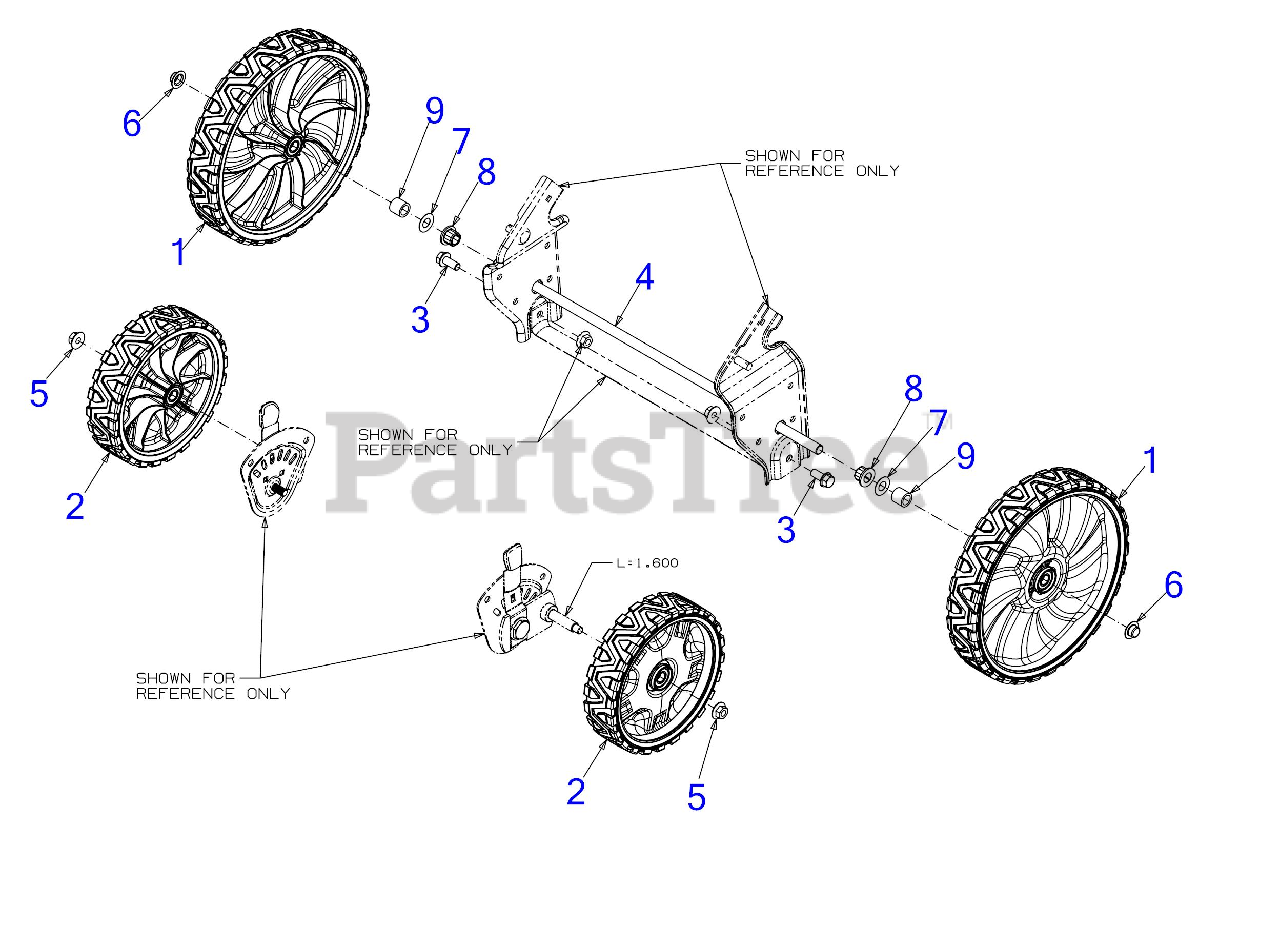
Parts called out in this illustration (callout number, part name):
1	WHEEL ASSEMBLY (11 x 2)
2	WHEEL ASSEMBLY (8 x 2)
3	SCREW 3/8-16 x .875 GR5
4	REAR AXLE .50 x 22.53 CSV
5	FLANGE LOCK NUT
7	FLAT WASHER
8	HEX FLANGE BEARING .506ID x .590LG
9	SPACER-.513 ID x .703 OD x .69
